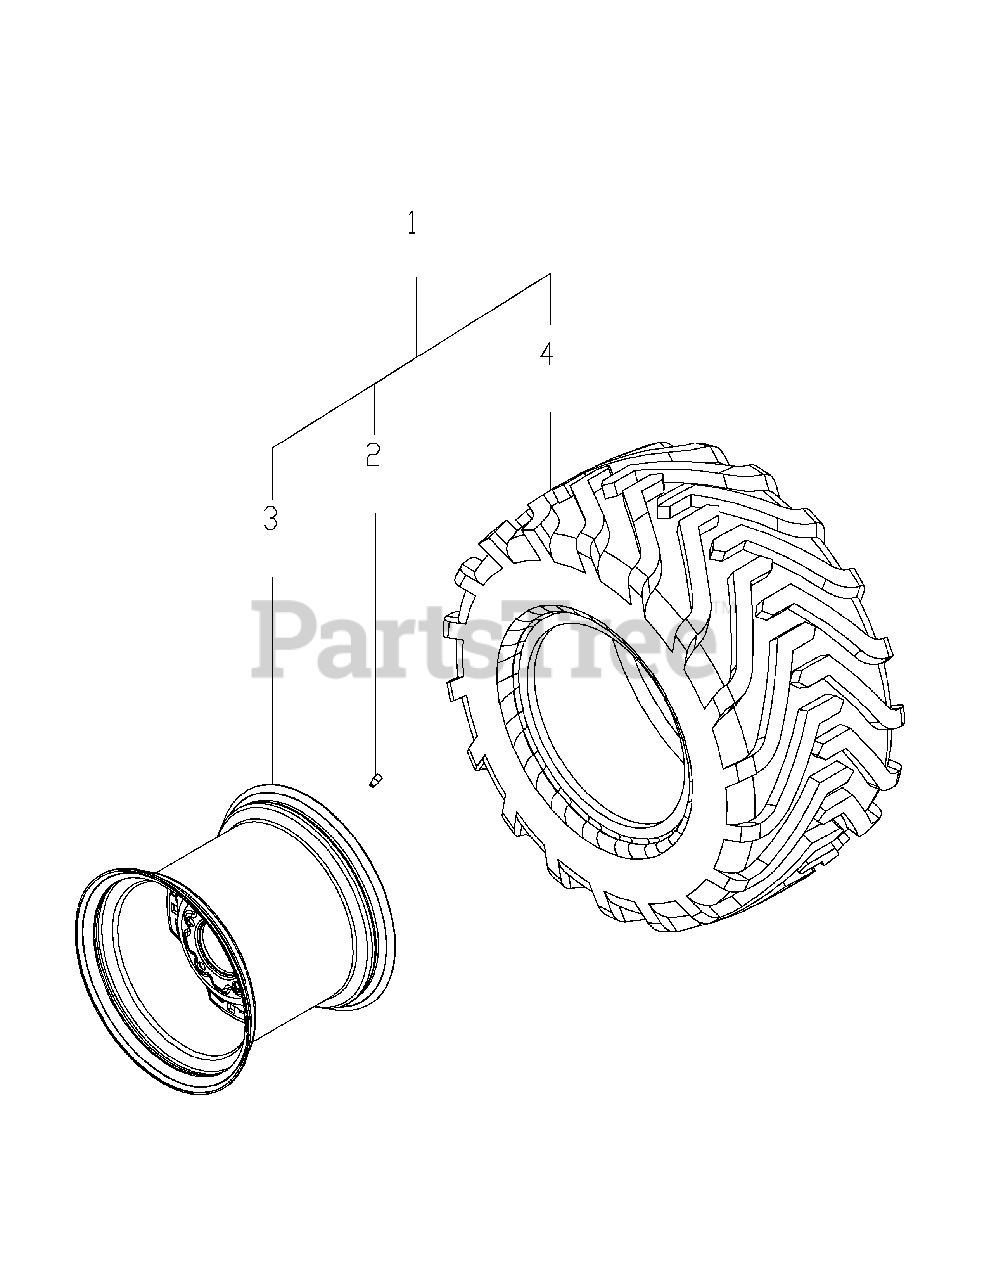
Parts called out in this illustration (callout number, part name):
1	TIRE ASM-REAR AG LH
1	TIRE ASM-REAR AG RH
4	TIRE,26X12-12 R1
